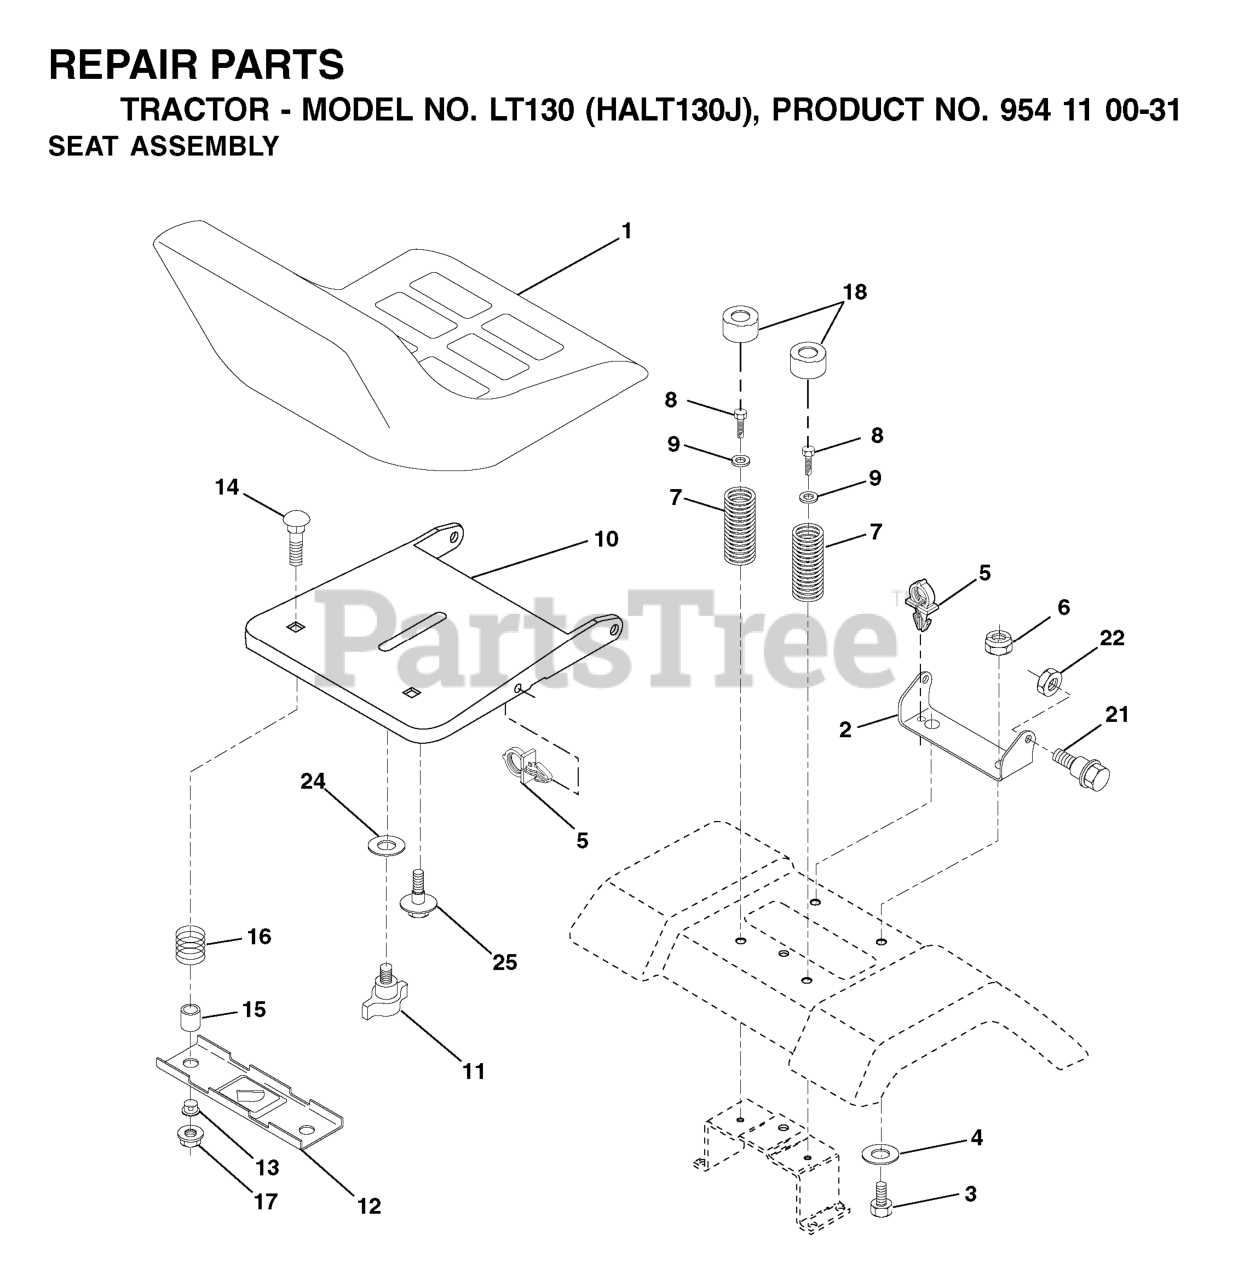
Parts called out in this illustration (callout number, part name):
2	MUFFLER.ASM.TWN.EXTNDED.DFLCTR
9	KEEPER BELT ENGINE
11	CLUTCH.OGURA.5.0PD.GT1.5A-EH07
12	PULLEY.ENGINE.TUFFTORQ
18	CAP.ASSY.FUEL.3".N-EPA.GRY.498
20	CONTROL.THROTTLE/CHOKE.PRO.45
21	SCREW.#10 X 0.750.BOS
28	LINE.FUEL.64"REAR.EMIS
29	KIT.SPARK ARRESTOR 794945 B&S
37	HOSE CLAMP
42	LOCKWASHER
45	NUT
62	SHIELD.HEAT.MUFFLER
69	GASKET.MUFFLER
70	EXHAUST.TUBE.LH.BS/TWIN
71	EXHAUST.TUBE.RH.B&S.TWIN.INTEK
79	SCREW.SOCKET.HEAD.5/16-18
81	TUBE, DRAIN OIL ASM.
82	VALUE.OIL.DRAIN
84	SCREW.3/8-16
85	BOLT HEX 7/16-20 X 3.75 GR. 5
90	SCREW 3/8-16X1
91	BUSHING.1.375OD
102	SCREW
116	KNOB - SHIFT
117	VALVE FUEL RESERVE
